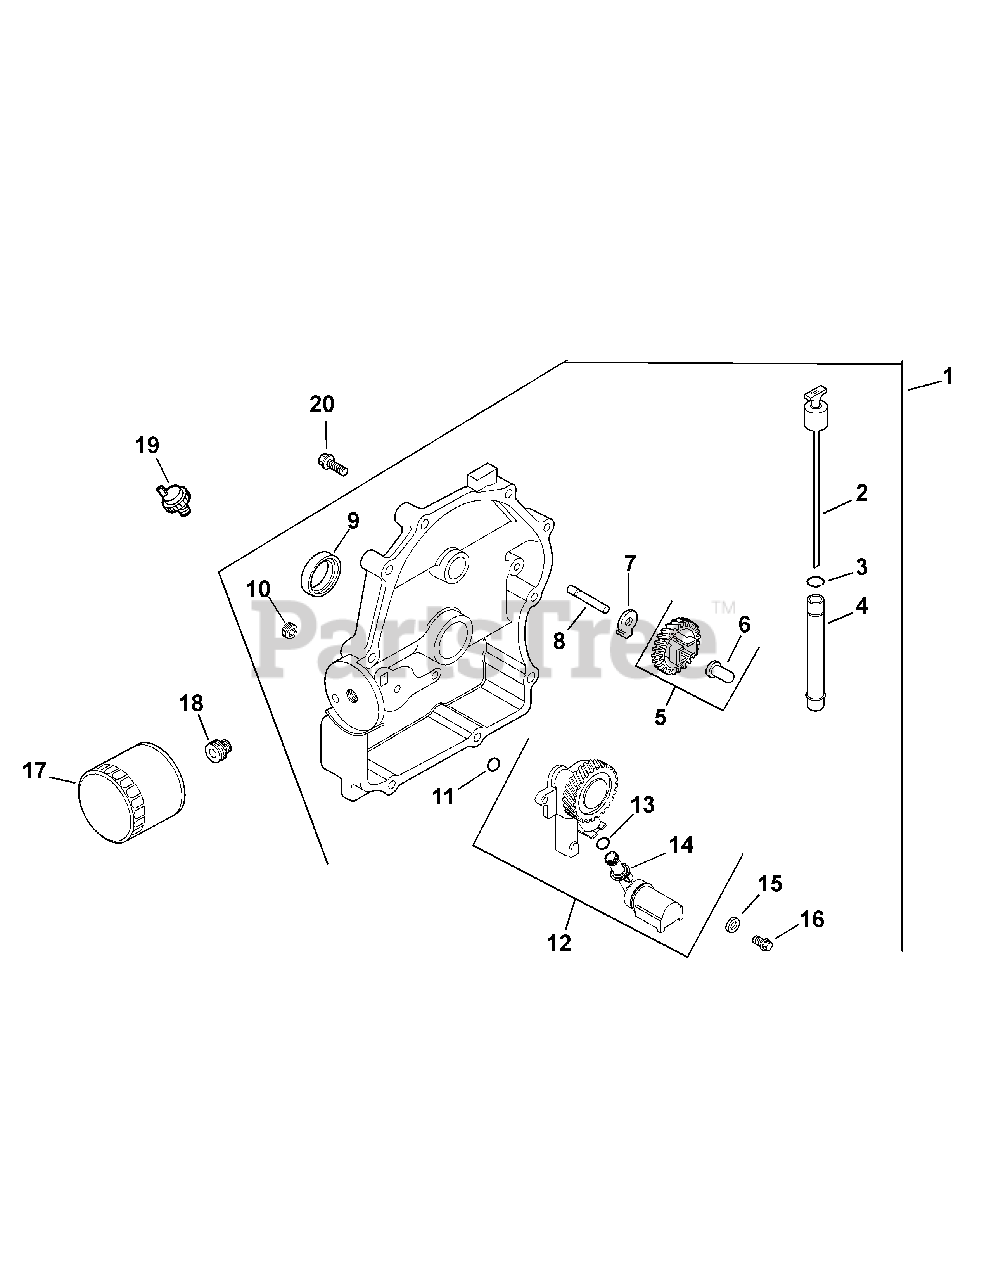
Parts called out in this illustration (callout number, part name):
1	Kit, Closure Plate Ass’y (Inc. 2-15)
4	Kit, Oil Fill Tube
5	Kit, Governor Gear w/ Pin (Inc. 6)
6	Pin, Governor Regulating
8	Shaft, Governor Gear
10	Plug, Pipe CTSK 1/8"
12	Kit, Oil Pump Assembly (Inc. 13, 14)
13	O-Ring, Oil Pick-Up
14	Pick-Up, Oil
15	Washer, Flat 6MM
16	Screw, Flg Thd Frm M6X1.0X25
18	Nipple, Oil Filter
19	Switch, Oil Pressure
20	Screw, Flg M8x1.25x45
